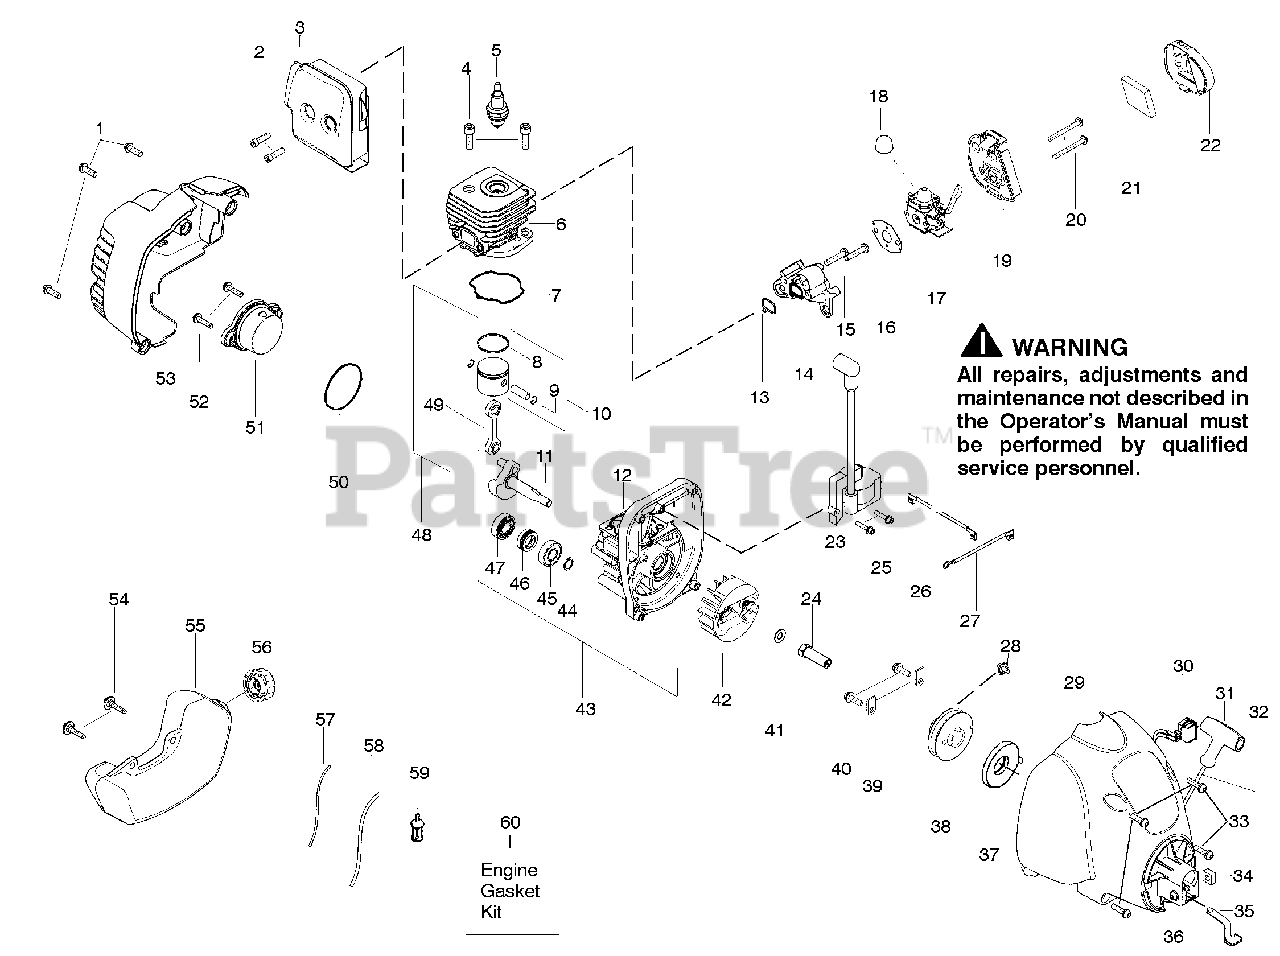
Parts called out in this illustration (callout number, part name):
2	Bolt-Muffler
3	Assy-Muffler/Shield
4	Screw-Cylinder
5	Spark Plug (RCJ 6Y)
6	Cylinder
7	Seal-Cylinder (kit)
8	Piston Ring
9	Retainer-Piston Pin
10	Kit - Piston
11	Assy-Crankshaft
12	Assy-Crankcase
13	Seal-Cyl/Carb.(kit)
14	Adapter-Carb.
16	Gasket-Carb. (kit)
17	Kit-Carb., Zama (C1U-W24)
17	Kit-Carb., Walbro ( WT-670)
18	Bulb - Purge, Zama
18	Bulb - Purge, Walbro
19	Air Box
21	Foam-Air Filter
22	Cover-Air Box
23	Ignition Module
24	Coupling-Drive
26	Assy-Leadwire
27	Assy-Ground Wire
29	Assy.-Fan Hsg
30	Kit-Switch
31	Handle-Starter
32	Kit - Rope
35	Clip-Spring
37	Spring-Starter
38	Kit-Pulley-Starter
39	Retainer-Pulley
41	Washer-Flat
42	Assy-Flywheel
43	Assy-C'case & C'shaft
44	Retain. Ring-C'shaft
45	Outer Bearing
46	Seal-C'case
47	Inner Bearing
48	Kit-piston/rod
49	Assy-Connecting Rod
50	O-Ring-C'case (kit)
51	Assy-Plug
53	Shroud-Rear
54	Retainer-Tank
55	Assy-Fuel Tank
56	Assy-Fuel Cap
57	Kit-Fuel Line (Small)
58	Kit-Fuel Line (Large)
59	Assy-Fuel Pickup
60	Kit-Engine Gasket
